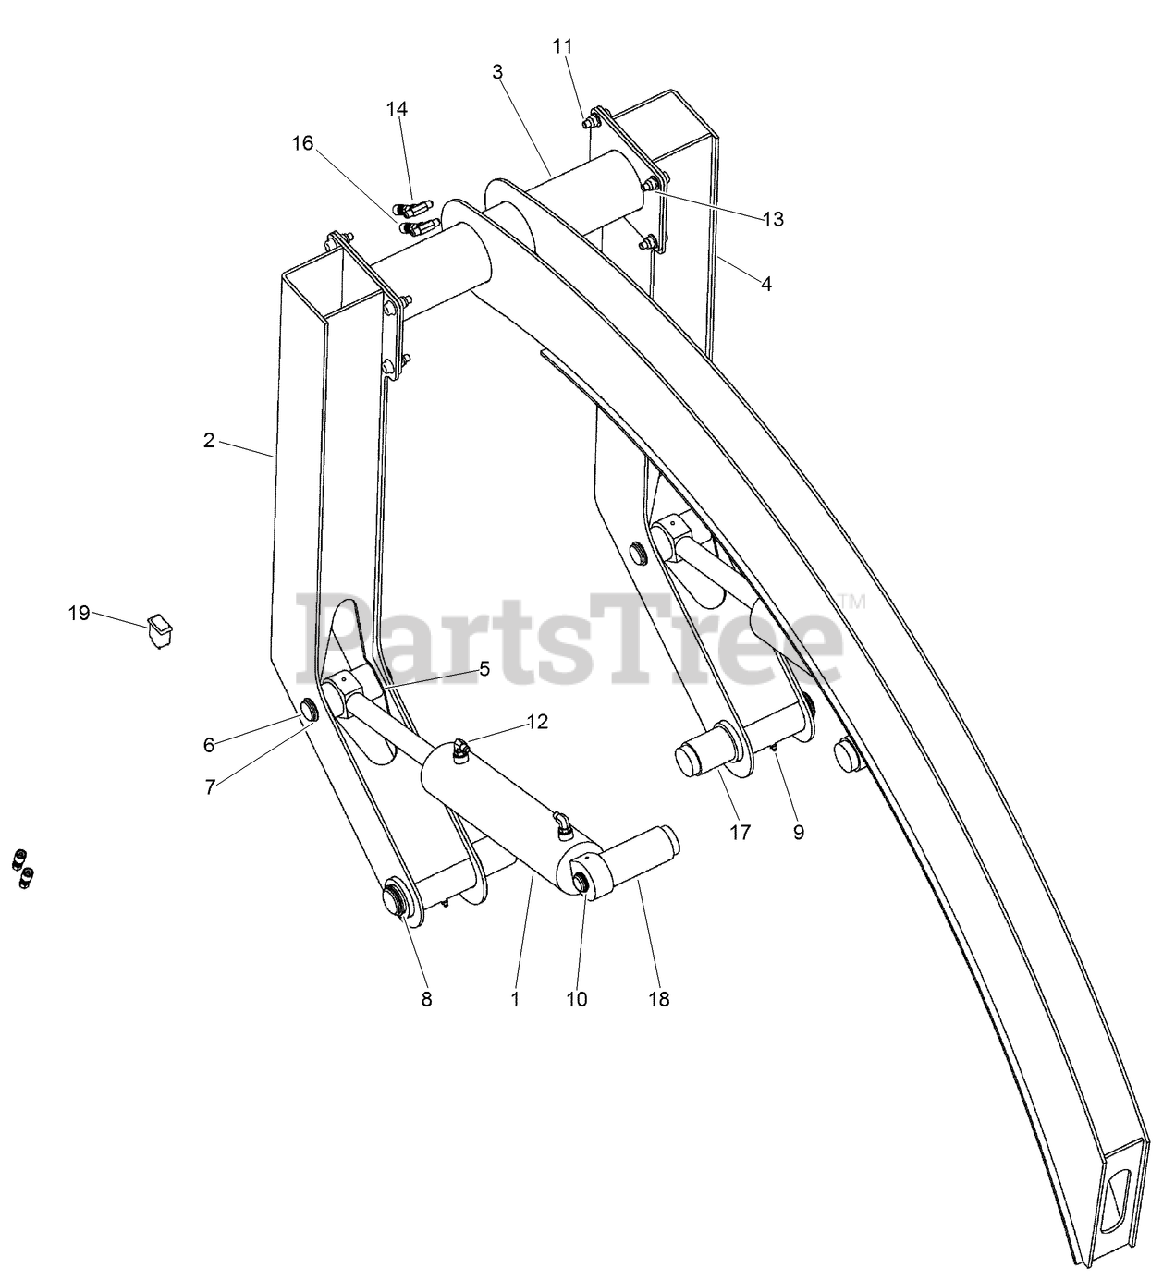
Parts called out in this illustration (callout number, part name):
1	CYLINDER ASSEMBLY - 89 (3-1/2) ID x 290 mm (11-13/32 inch) Stroke, Plow Lift
2	ARM - Crumber
3	GUARD - Crumber
4	ARM - Crumber
5	BUSHING - Pivot
8	RING-RETAINING, EXTERNAL
9	FITTING-Lube 1/8-27 Dryseal PTF
10	RING-RETAINING
12	ELBOW-90 DEG (ADJUSTABLE 37 DEG)
13	NUT-HHF, LOCK
14	TEE - Bulkhead BR 37FL 3/8 x 3/8 x 3/8
16	FITTING
19	SWITCH-ROCKER, 2 POLE
